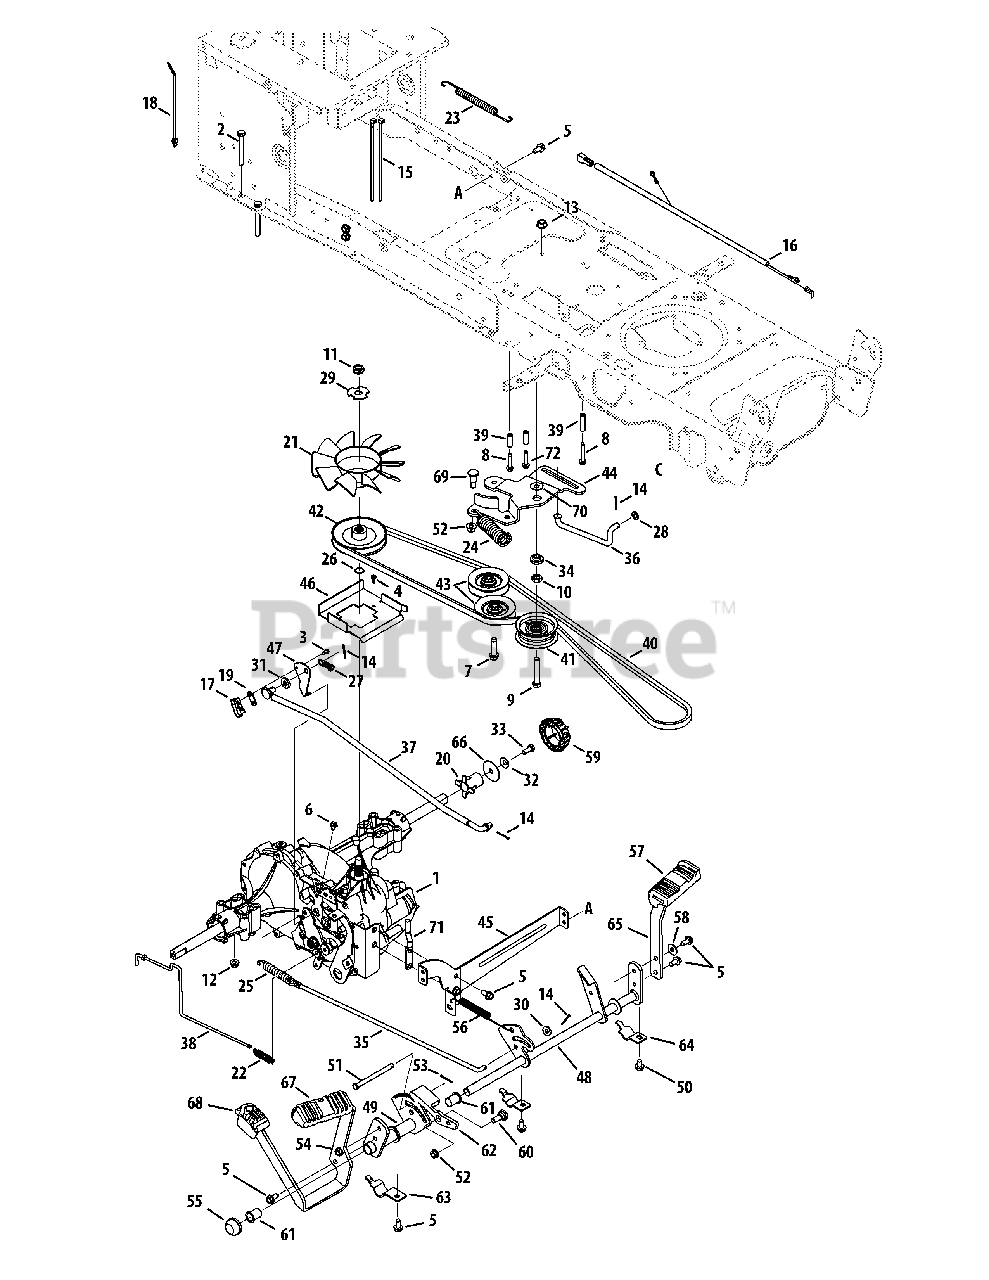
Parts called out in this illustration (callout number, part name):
1	Transmission, Hydro-Gear
2	Hex Screw, 5/16-18, 2.75, Gr5, Std
3	Screw, #8-18, 0.500,
4	Screw, #10-16, 0.500
5	Screw, Self-tapping, 5/16-18, .750
6	Screw, Self-tapping, 1/4-20, 0.375
7	Screw, Self-tapping, 3/8-16, 1.500
8	Screw, Self-tapping, 1/4-20, 1.625
9	Hex Screw, 3/8-16, 2.25, Gr5
10	Nut, Jam, 7/16-20, Gr2
11	Nut, Jam Lock, 1/2-20, Gr5, Nylon
12	Nut, Flange Lock, 5/16-18, Nylon
13	Nut, Flange Lock, 3/8-16
14	Pin, Cotter, 3/32, 1.0
15	Cable, Tie, 3/16 x .05 x 7.4
16	Jumper Harness, Ground & Reverse
17	Switch, Spring, Short
18	Tie, Cable, Push Mount 7.5
19	Plate, Insulator Nut
20	Sleeve, .765 Id x 1.500
21	Fan, Hydro
22	Spring, Extension, .48 Od x 2.03
23	Spring, Extension, .500 Dia x 12.6
24	Spring, Extension, 1.00 Dia x 4.75
25	Spring, Extension, .59 Od x 4.00
26	Ring, Wire
27	Spring, Extension, .375 Od x 1.44
28	Washer, Flat, .330 x .630 x .0635
29	Washer, Lock, Transmission Hydro
30	Washer, Flat, .344 x .750 x .120
31	Washer, Flat, .407x.812x.135, Ht
32	Washer, Bell, .340 x .872 x .060
33	Hex Screw, 5/16-24, .750, Gr5, Lock
34	Spacer, Shoulder, 1.375 x .380 x .183
35	Rod, Brake, LT Hydro
36	Rod, Transmission, Bypass
37	Rod, Control, Hydro
38	Rod, Hydro Bypass
39	Spacer, .260 x .372 x 1.420
40	Belt, V-Type
41	Pulley, Idler, Flat 2.75 OD
42	Pulley, Input, 4.13 Dia
43	Pulley, Idler, V-Type x 3.06
44	Bracket, Idler, Center Double
45	Bracket, Mount, Hydro
46	Bracket, Support, Belt Disengage
47	Bracket, Actuator, Switch
48	Control Assembly, Brake
49	Bracket Assembly, Pedal, Hydro
50	Screw, Self-tapping, 5/16-18, 0.625,
51	Pin, Clevis, 5/16 x 3.985
52	Nut, Flange Lock, 3/8-16, Nylon
53	Pin, Cotter, Bow-Tie 72
55	Cap, Push 5/8
56	Spring, Extension, .63 Dia x 4.95
57	Pad, Pedal, Brake
58	Washer, Bell, .340 x .872 x .060
59	Cap, Hub
60	Bolt, Shoulder, .500 x .270, 3/8-16
61	Bearing, Flange, .630 x .695 x .60
62	Latch, Cruise
63	Bracket, Support, Pedal Strap
64	Bracket, Support, Pedal Strap 5/8
65	Bracket, Pedal, Brake
66	Washer, Flat, .350 x 1.59 x .062
67	Pad, Pedal, Forward
68	Pad, Pedal, Reverse
69	Screw, Shldr, .50 x .685 3/8-16
70	Washer, Flat, .385 x 1.0 x .030
71	Belt Keeper Rod
72	Screw, Self-tapping, 1/4-20 x 1.75
